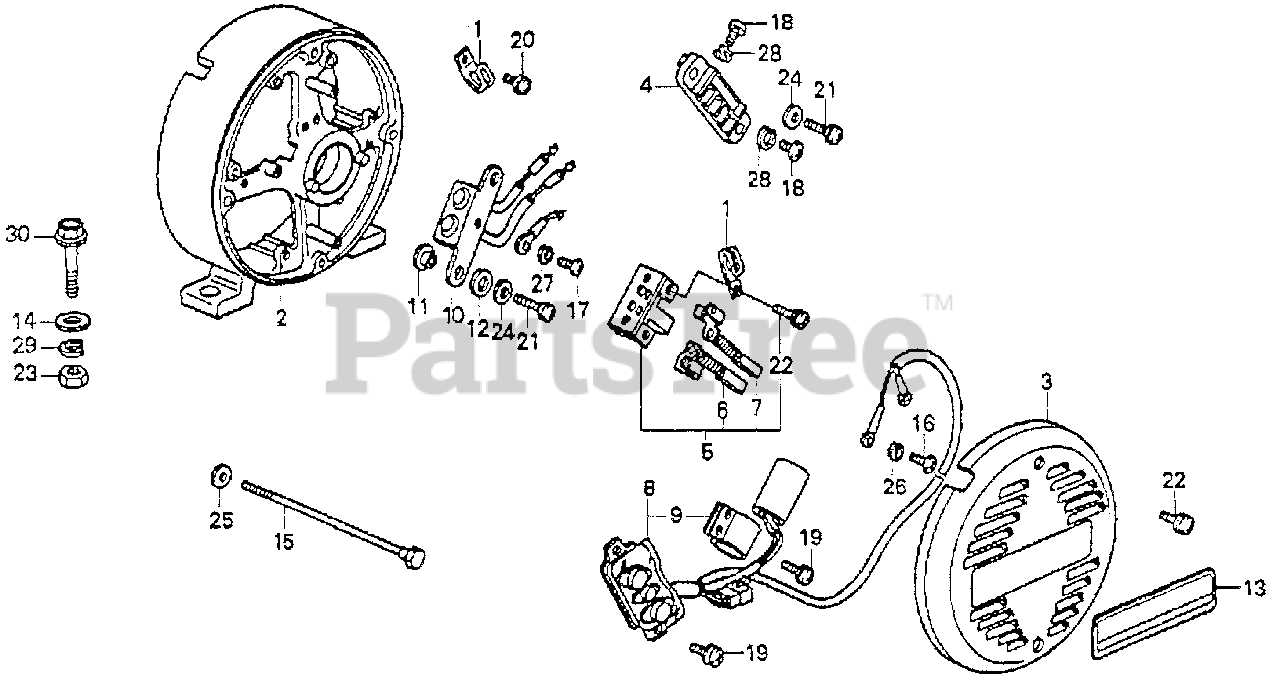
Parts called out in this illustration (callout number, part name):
1	CLAMP B, WIRE
2	HOUSING, RR. *NH31* (MCKINLEY WHITE)
3	COVER, GENERATOR *R8* (BRIGHT RED)
4	TERMINAL, A.C. OUT
5	HOLDER ASSY., BRUSH
8	REGULATOR ASSY., AUTOMATIC VOLTAGE
9	HOLDER, CONDENSER
10	DIODE ASSY., D.C. (NOT AVAILABLE)
11	BUSH, INSULATING
12	WASHER, INSULATING
13	MARK, PLATE
14	WASHER, EX. MANIFOLD
15	BOLT, HEX. (6X190) (SOURCE: VINTAGE PARTS INC.)
16	SCREW, PAN (4X8)
17	SCREW, PAN (5X8)
18	SCREW, PAN (6X8)
19	SCREW-WASHER (5X12)
20	SCREW-WASHER (5X10)
21	SCREW-WASHER (5X20)
22	SCREW-WASHER (5X10)
23	NUT, HEX. (10MM)
24	WASHER, PLAIN (5MM)
25	WASHER, PLAIN (6MM)
26	WASHER, SPRING (4MM)
27	WASHER, SPRING (5MM)
28	WASHER, SPRING (6MM)
29	WASHER, SPRING (10MM)
30	BOLT, FLANGE (10X32)
